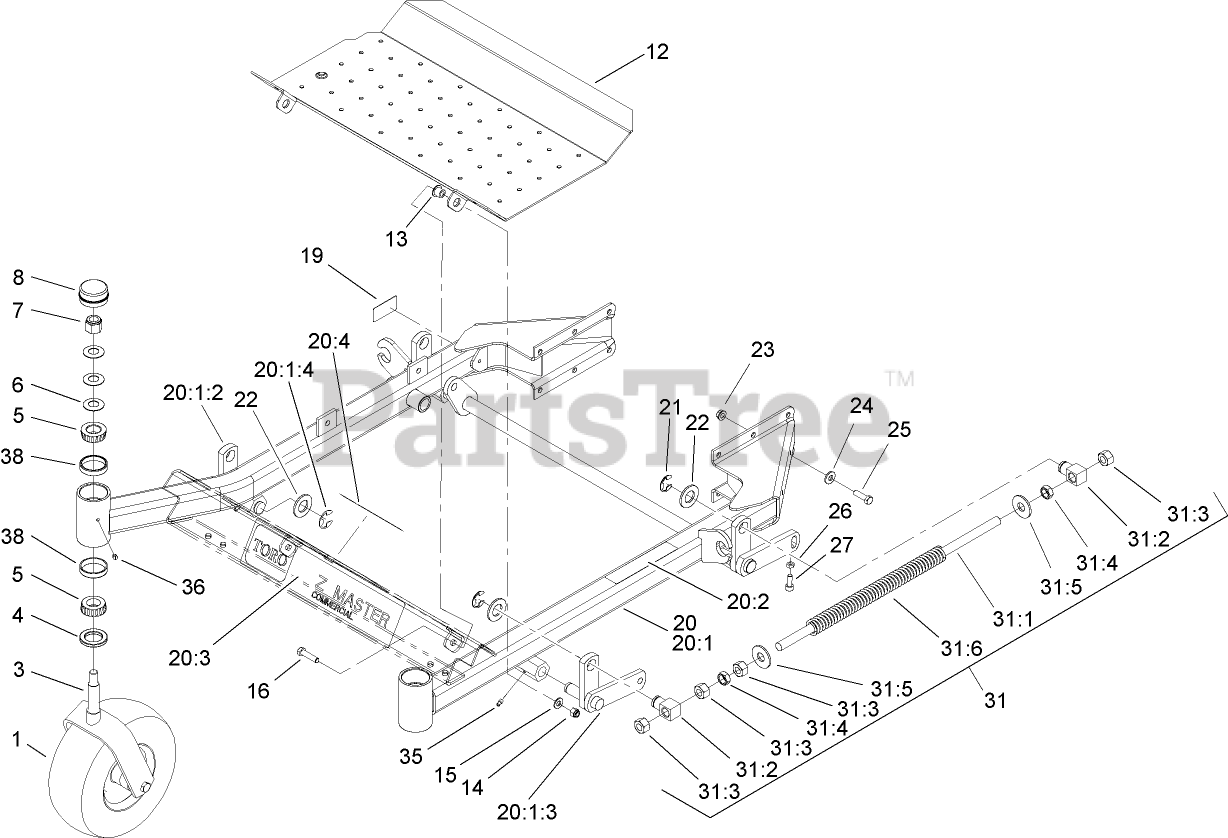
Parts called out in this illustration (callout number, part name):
1	CASTER WHEEL ASM
3	CASTER
4	SEAL-GREASE
5	BEARING-CONE, TAPERED
6	WASHER-BELLVILLE
7	NUT-LOCK, NI
8	CAP-GREASE
12	PAN-FLOOR
13	BUSHING-FLANGE
14	NUT-LOCK, NI
15	WASHER-FLAT
16	SCREW-HH
19	DECAL-STD, SAFETY
20	FRONT FRAME ASM
20:1	FRAME-FRONT
20:1:2	RH LIFT ARM ASM
20:1:3	LH LIFT ARM ASM
20:1:4	RING-RETAINING, EXT
20:2	DECAL-WARNING
20:4	DECAL-WARNING
21	RING-RETAINING, EXT
22	WASHER-FLAT
23	NUT-HHF, WHIZ
24	WASHER-BELLEVILLE
25	SCREW-HH
26	NUT-JAM
27	SCREW-HSH
31	FRONT FRAME SPRING ASM
31:1	ROD-LIFT, DECK
31:2	SWIVEL-DECK MOUNT, REAR
31:3	NUT-HEX
31:4	NUT-JAM
31:5	WASHER-FLAT
31:6	SPRING-SUPPORT, DECK
35	FITTING-GREASE
38	BEARING-CUP, TAPERED
